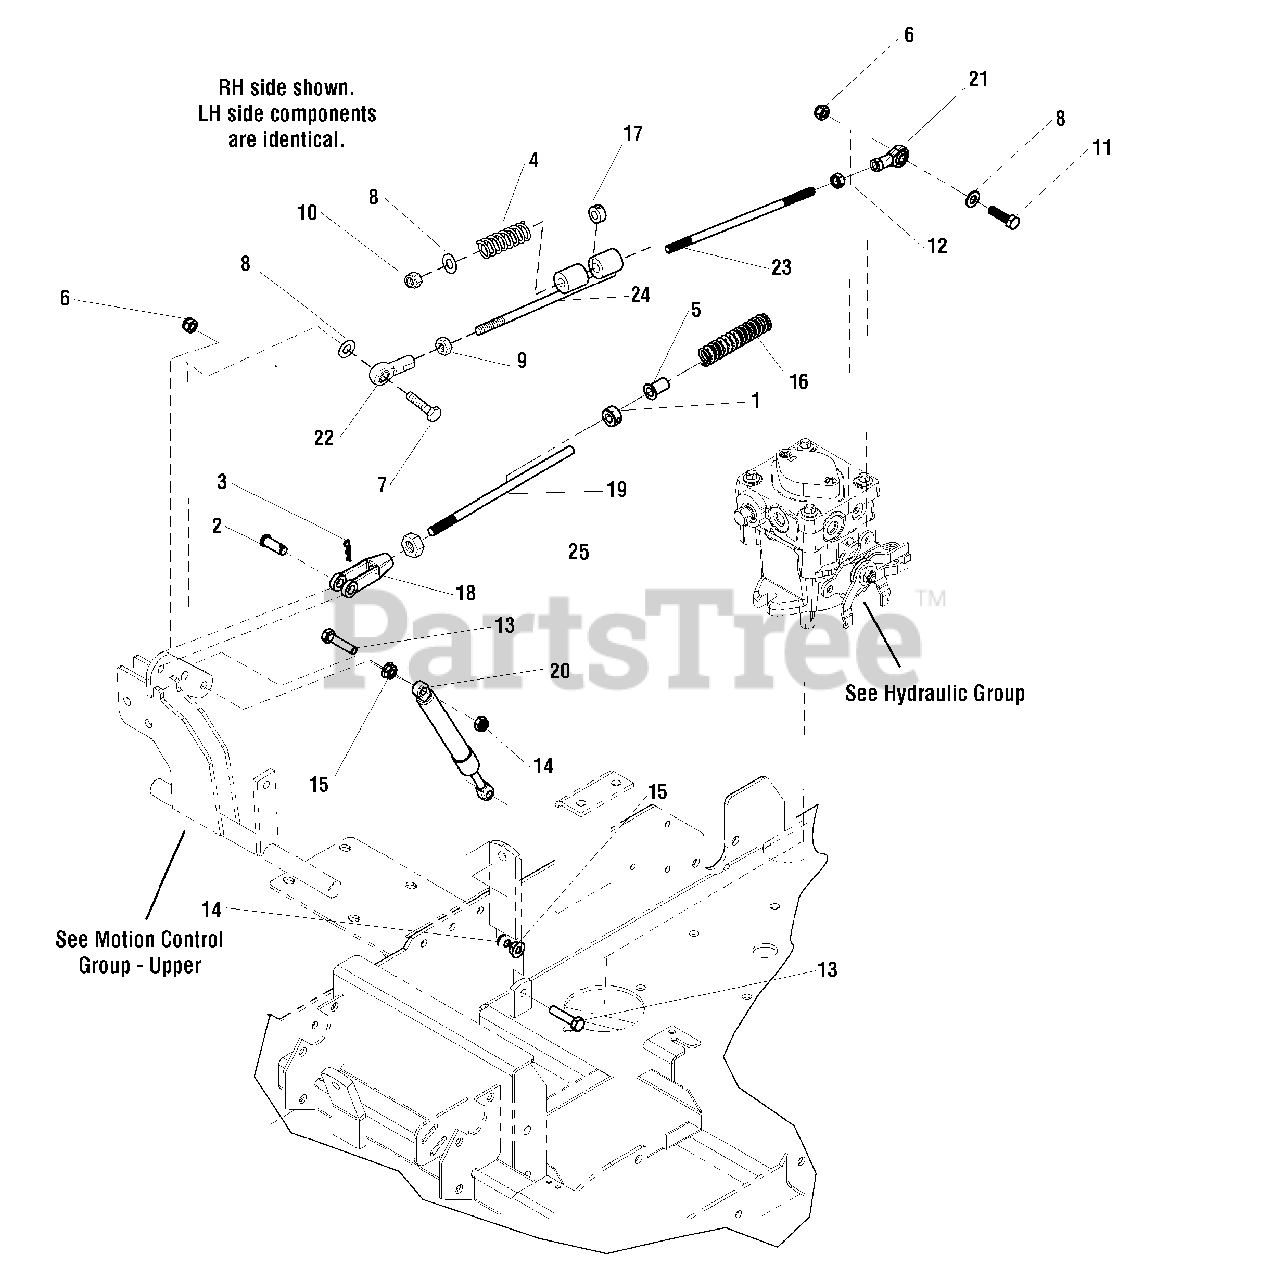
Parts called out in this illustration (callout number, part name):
1	COLLAR, 3/8" SET
2	PIN, CLEVIS, 3/8" X 1"
3	PIN, HAIR, .0585 X 1-1/8
4	SPRING, CONTROL ROD
5	BUSHING, FLANGE 3/8ID X 7/8 LONG
6	NUT 5/16-18 HEX NYLON LOCK
7	BOLT, 5/16-18 X 1-1/4" GD5
8	WASHER, 5/16" SAE
9	NUT, HEX 5/16-24
10	NUT 5/16-24 HEX NYLON LOCK
11	BOLT, 5/16-18 X 1" GD5
12	NUT, 5/16 HEX LH
13	BOLT, M8-1.25 x 35MM
14	NUT, M8-1.25 Hex Nylon Lock
15	NUT, M8-1.25 Hex Serrated Flange
16	SPRING, COMPRESSION
17	SET COLLAR, 5/16"
18	CLEVIS, 3/8-24, PLASTIC
19	ROD, NEUTRAL CONTROL, 8"
20	DAMPENER
21	BALL JOINT 5/16-24 LH FEMALE STAMPED STL
22	BALL JOINT 5/16-24 RH FEMALE STAMPED STL
23	ROD, 5/16 X 8.38, LH-RH, CZ
24	ROD ASSEMBLY, SLIDER
25	NUT, 3/8-24 HEX
